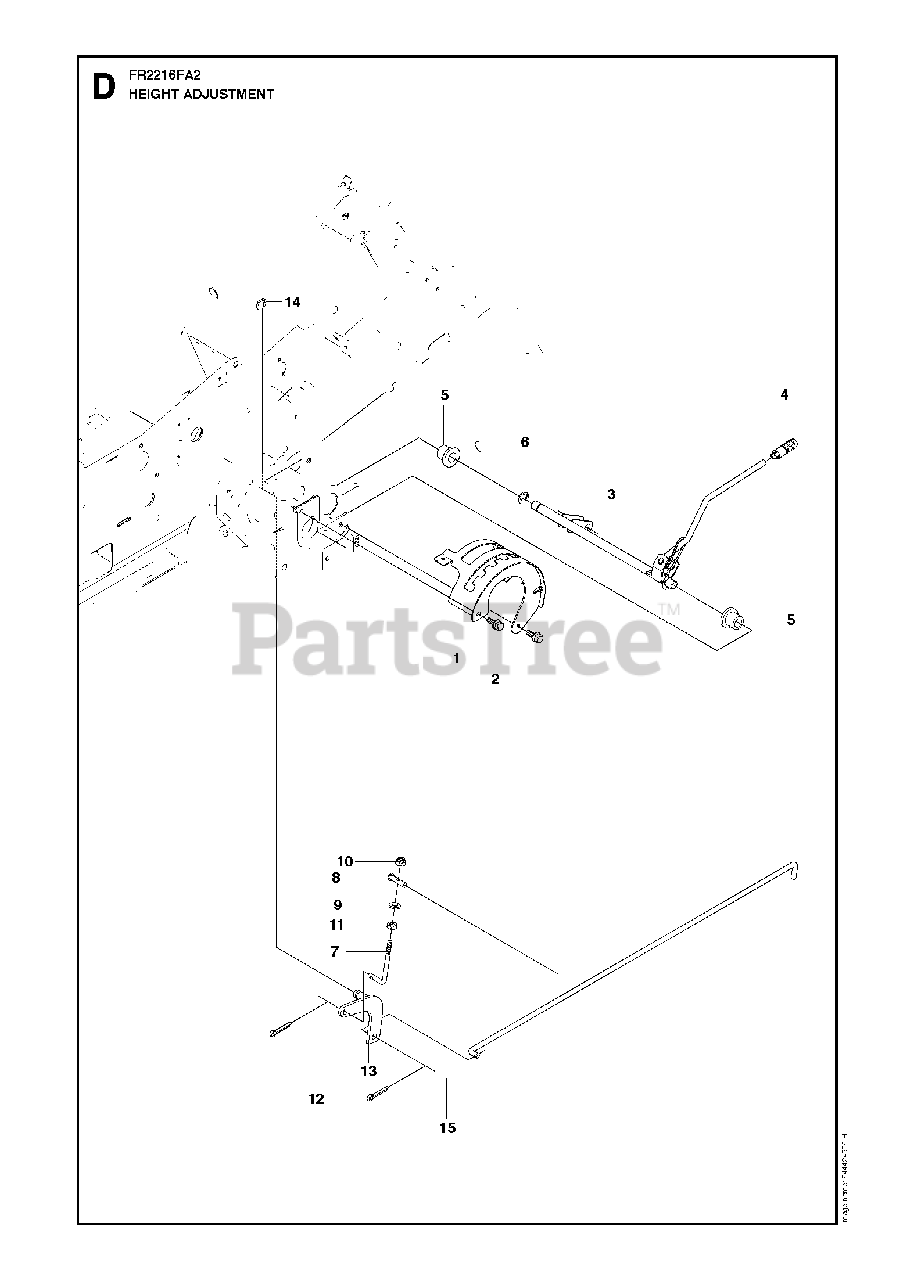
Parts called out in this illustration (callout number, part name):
1	CONTROL PLATE
4	GEAR STICK KNOB
5	BUSHING
9	WASHER
10	LOCKNUT M8
11	NUT
12	SPLIT PIN
14	RETAINING RING
15	CONNECTION ROD
